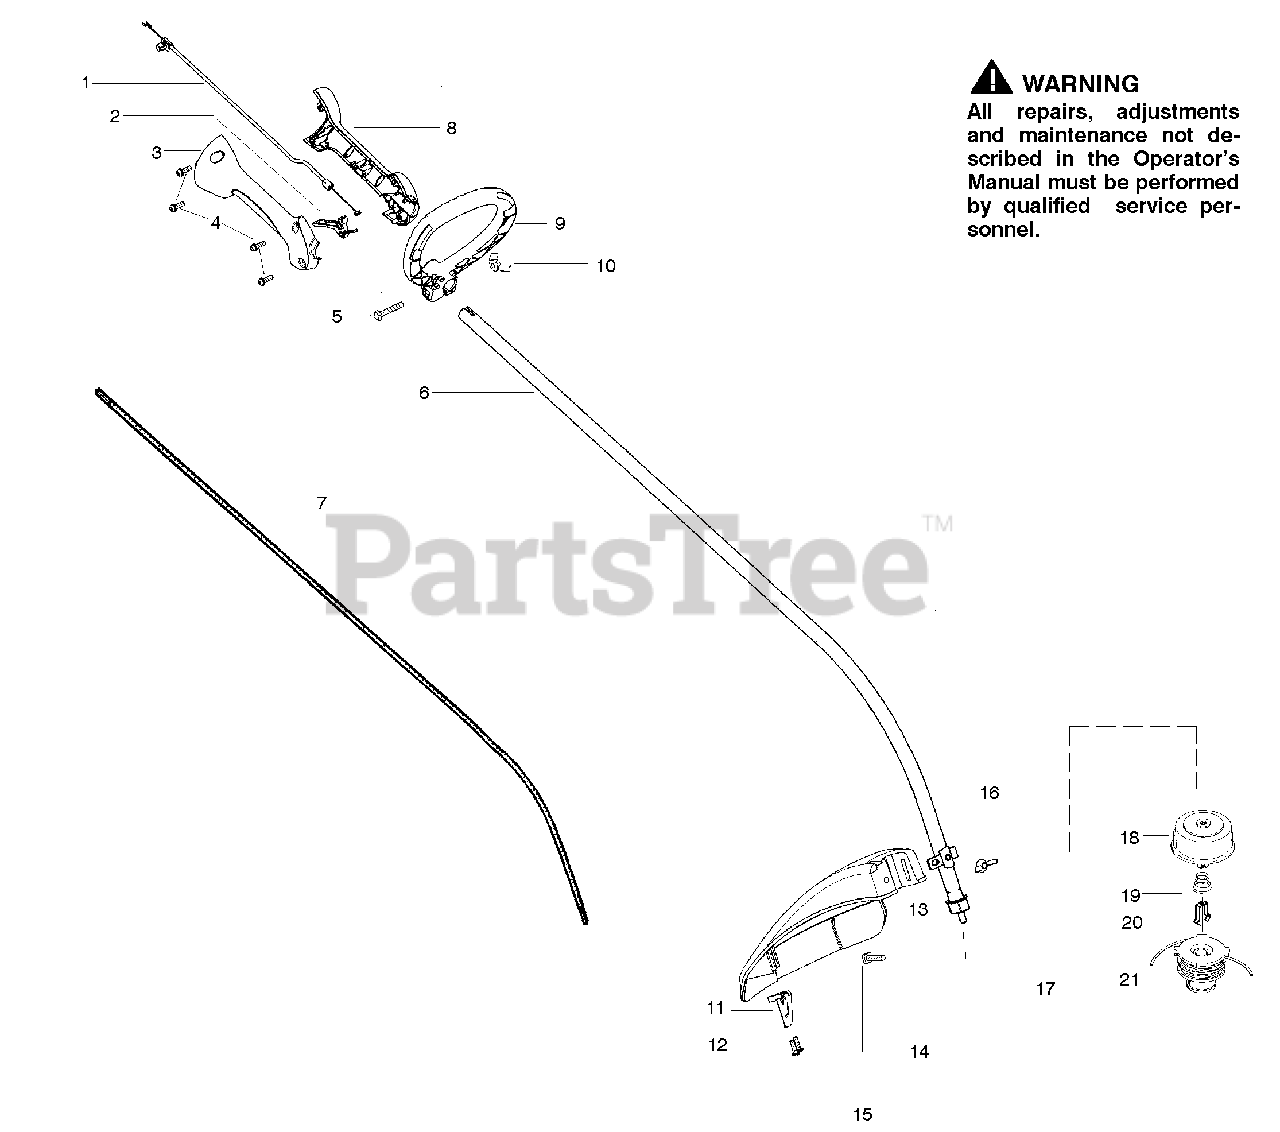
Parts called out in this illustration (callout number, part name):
1	Assy-Throttle Cable
3	Throttle Hsg. (Right)
4	Screw-Throttle Hsg.
5	Bolt-Handle/Shield
6	Kit-Drive Shaft Hsg.
7	Shaft- Flex
8	Throttle Hsg. (Left)
9	Assy-Handle
10	Wingnut
11	Line Limiter
12	Screw-Line Limiter
13	Dust Cup
15	Kit-Shield Assy
16	Wingnut
17	Accy-TNG VI Cutting Head
18	Assy-Hub
19	Spring-Compression
20	Clip-Retainer-Head
21	Accy- Spool w/Line
